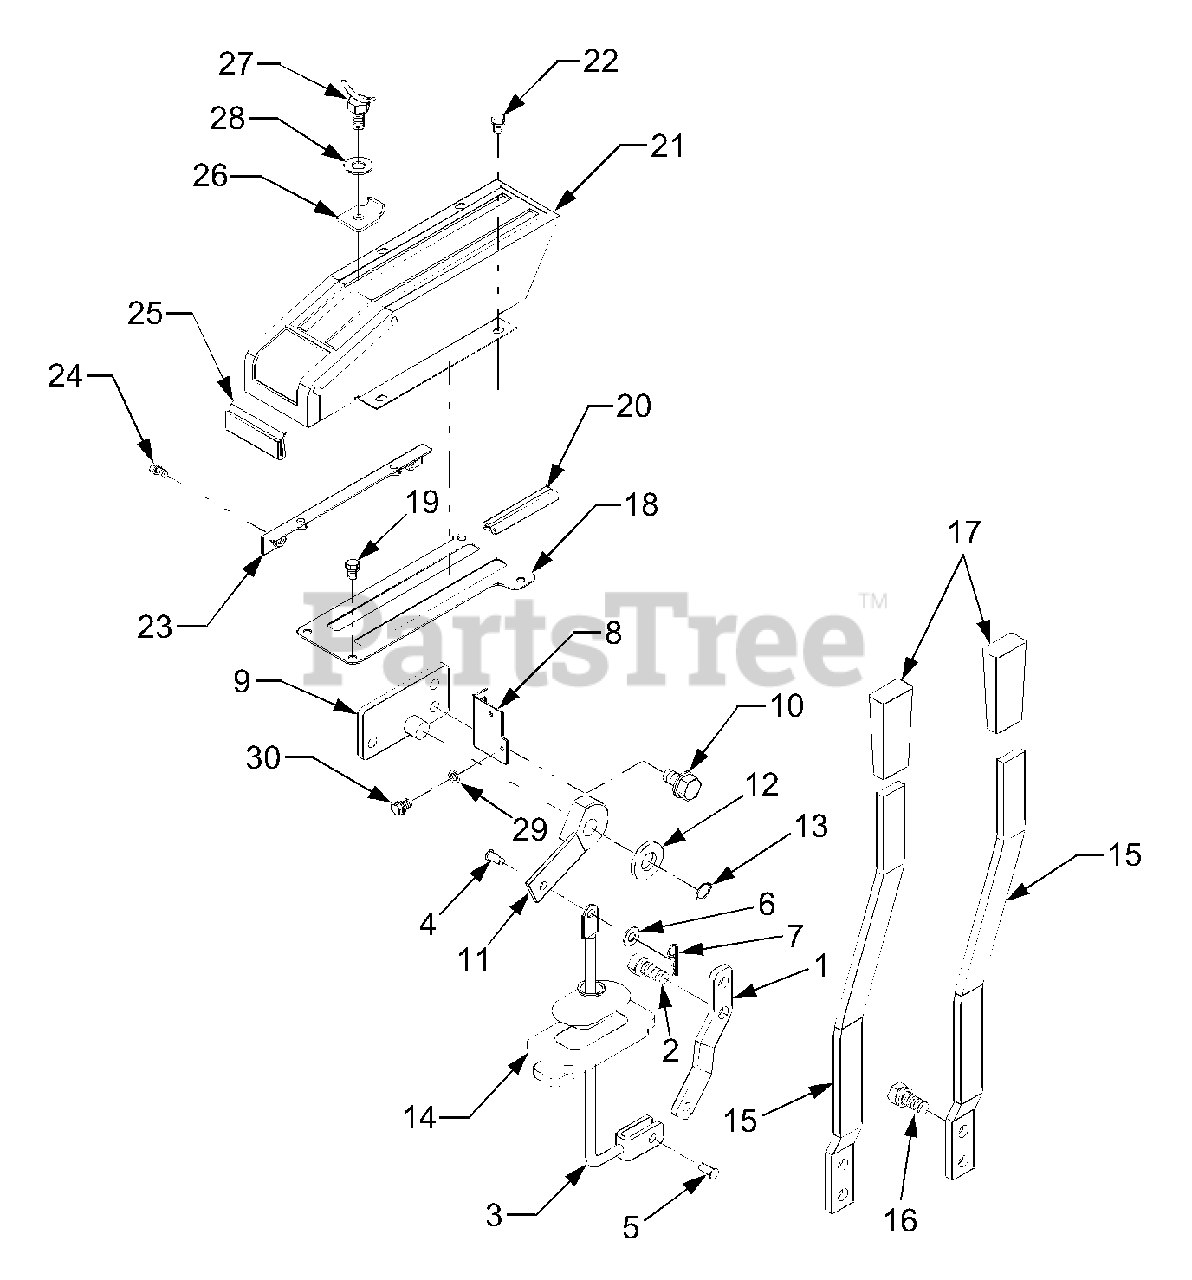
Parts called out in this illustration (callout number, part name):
1	Lever 1(Switch)
6	Washer, Plain
9	Plate(Switch)
11	Lever 2 (Switch)
12	Washer, Plain
14	Boot(PTO Switch)
15	Lever, Position Control
18	Plate(Position, Draft)
21	Guide, Hydraulic Lever
23	Bracket, Guide
25	Rubber (Guide)
28	Washer, Plain
29	Washer, Plain
